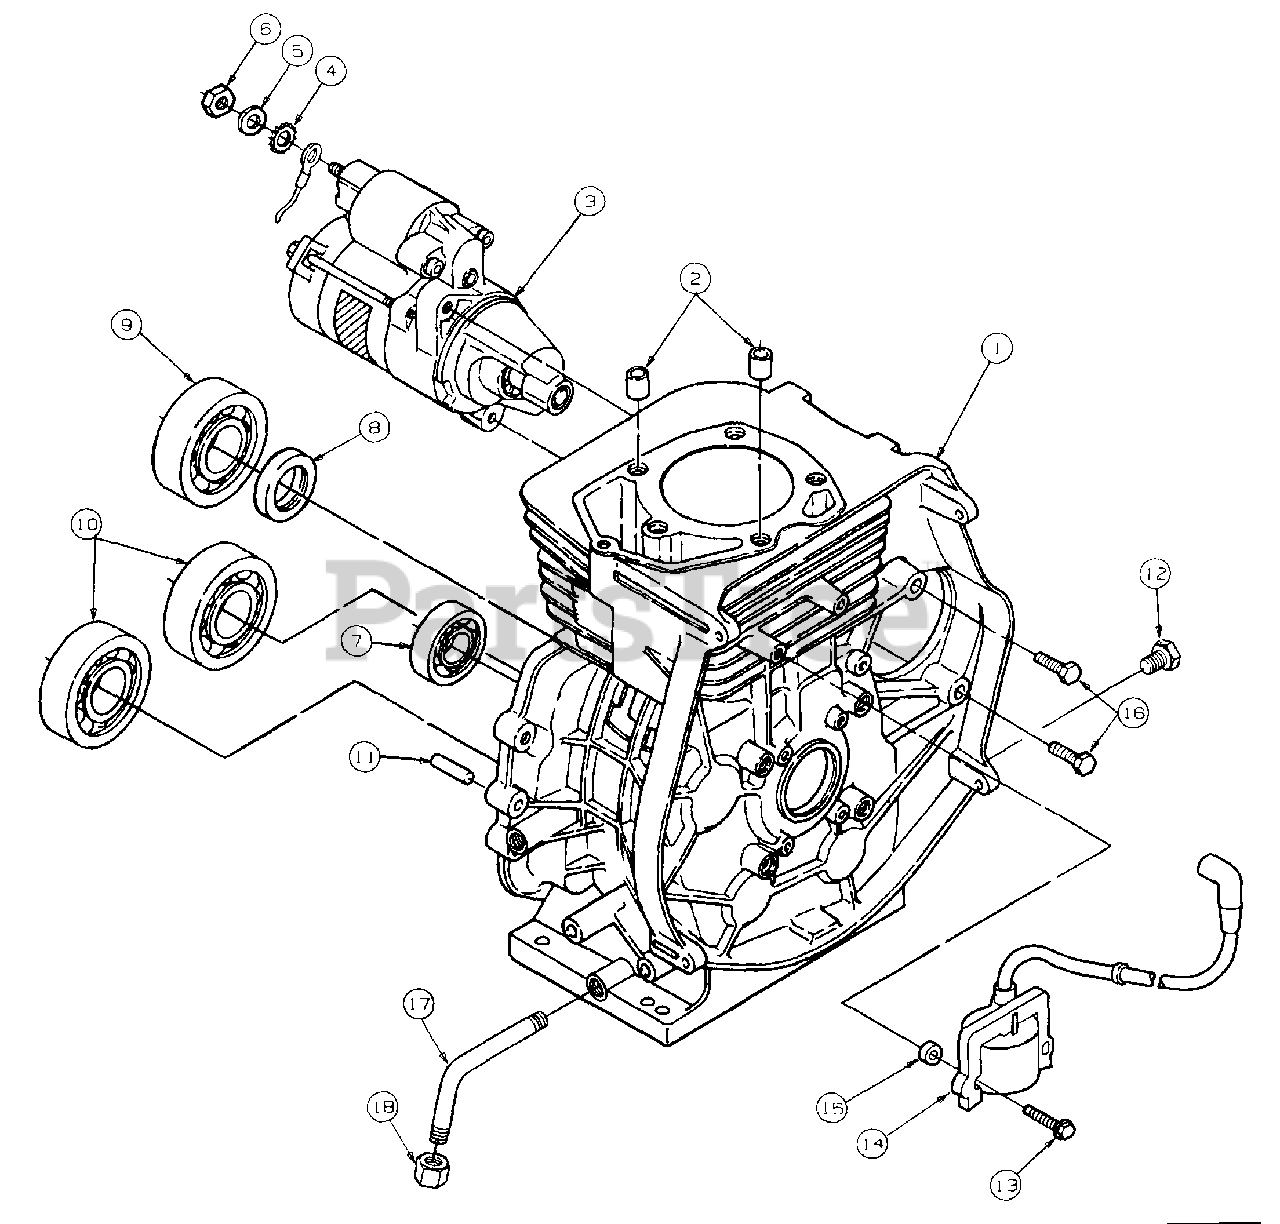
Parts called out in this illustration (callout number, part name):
1	Engine, Complete
2	Pin, Hollow Dowel
3	Starter
4	Washer, Lock, ET
5	Washer, Flat
7	Bearing, Camshaft
8	Seal, Crankshaft Oil
9	Bearing, Crankshaft
10	Bearing, Balancer Shaft
11	Pin, Alignment
12	Plug, Oil Drain
13	Screw, Pan Head M6 x 1 x 30 mm
14	Coil, Ignition
15	Spacer, Ignition Coil, M6 x 30 mm
16	Screw, Hex Head Cap, M8 x 1 x 40 mm
17	Pipe, Oil Drain
18	Cap, Oil Drain
